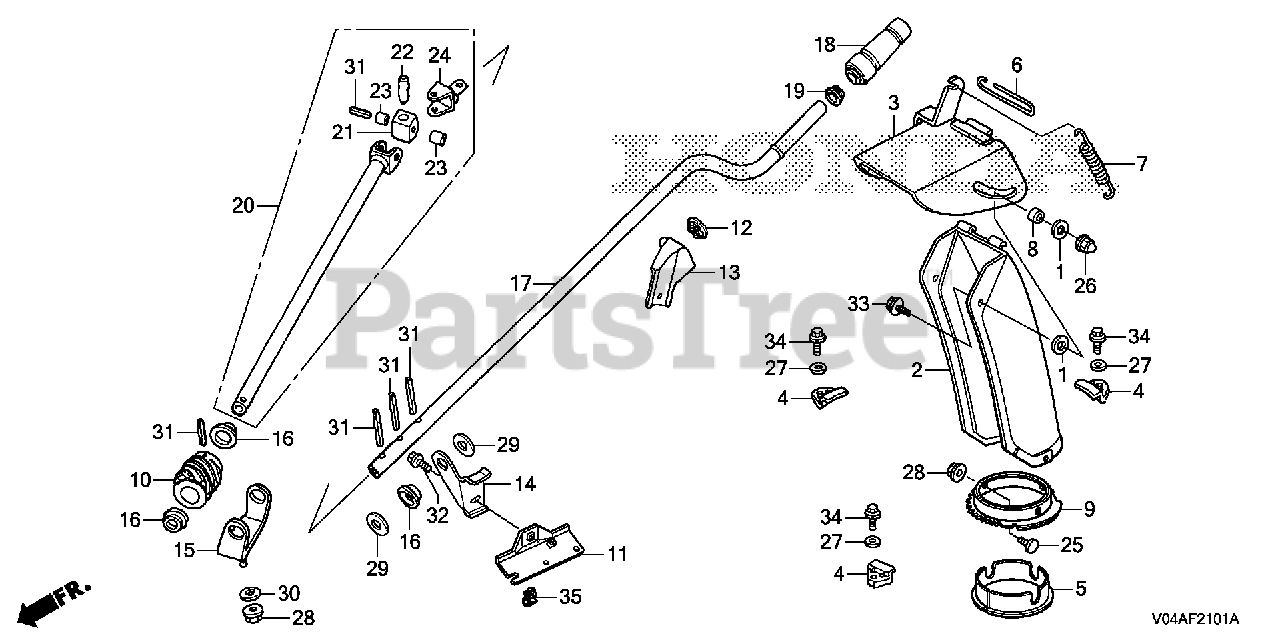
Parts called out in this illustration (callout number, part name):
1	WASHER, ACCELERATOR PEDAL
2	CHUTE
3	GUIDE, CHUTE (COO)
4	PLATE, CHUTE SETTING
5	BUSH, CHUTE
6	PIN, CHUTE GUIDE
7	SPRING, CHUTE
8	COLLAR, CHUTE GUIDE
9	GEAR, CHUTE
10	GEAR, CHUTE DRIVE
11	HOLDER, HANDLE BRACKET
12	BUSH, CHUTE HANDLE
13	BRACKET A, CHUTE HANDLE
14	BRACKET B, CHUTE HANDLE
15	STAY, DRIVE GEAR
16	BUSH, DRIVE GEAR
17	HANDLE, CHUTE (UPPER)
18	GRIP, CHUTE HANDLE
19	BUSH A, CHUTE HANDLE
20	HANDLE, CHUTE (LOWER)
21	PIECE, JOINT
22	PIN A, JOINT
23	PIN B, JOINT
25	BOLT, SPECIAL (8X15)
26	NUT, CAP (6MM)
27	WASHER, CHUTE SETTING
28	NUT, FLANGE (8MM)
29	WASHER, PLAIN (16MM)
30	WASHER, PLAIN (8MM)
31	PIN, SPRING (4X28)
32	BOLT, FLANGE (6X12)
33	BOLT, FLANGE (6X14)
34	BOLT, FLANGE (8X12)
